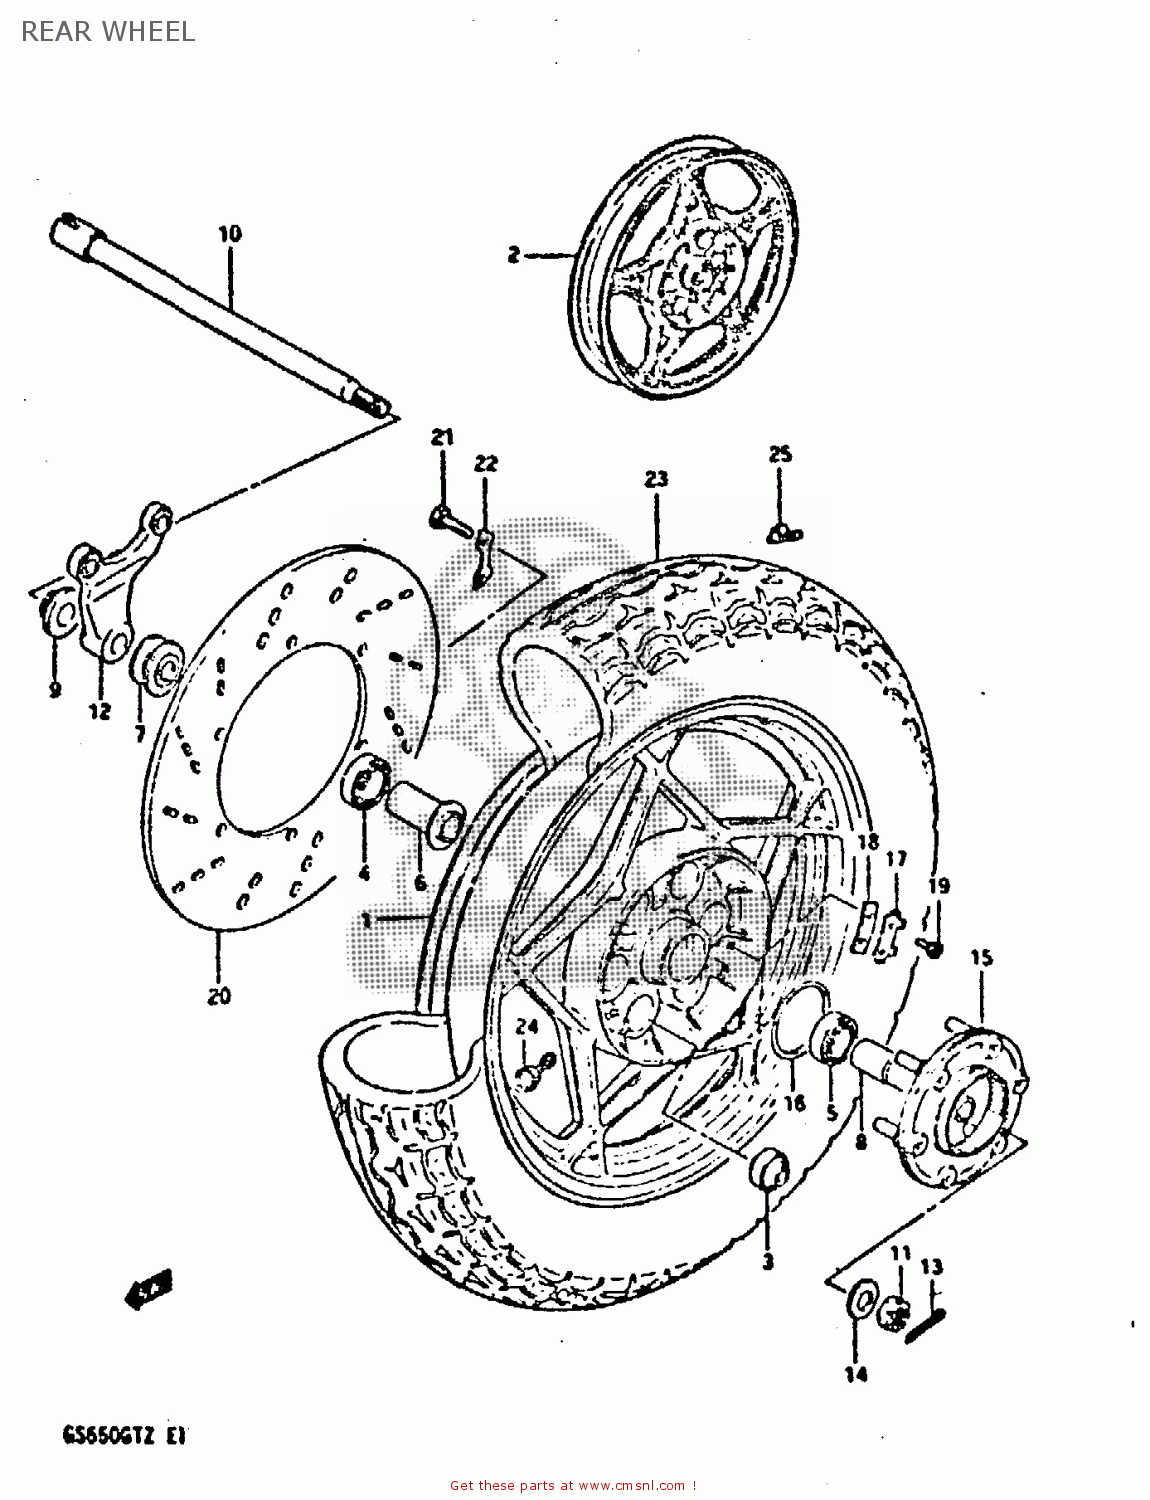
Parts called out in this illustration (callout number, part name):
1	WHEEL SET,REAR
2	CASTING WHEEL,REAR 2.50
3	BUSHING
4	BEARING
5	BEARING
6	SPACER,REAR HUB BEARING
7	SPACER,REAR AXLE
8	SPACER,REAR AXLE,LEFT
9	SPACER,REAR AXLE,RIGHT
10	AXLE,REAR
11	NUT
12	BRACKET,RR,CALIPER
13	PIN,COTTER
14	WASHER(16.5X36X3.2)
15	JOINT ASSEMBLY,REAR HUB DRUM
16	O RING(D:2.1,ID:65)
17	WASHER
18	WASHER,THRUST(T:1.6)
19	SCREW
20	DISC,RR BRAKE
21	BOLT(8X25)
22	WASHER
23	TIRE
24	VALVE ASSEMBLY,WHEEL RIM,J
25	BALANCER,WHEEL
